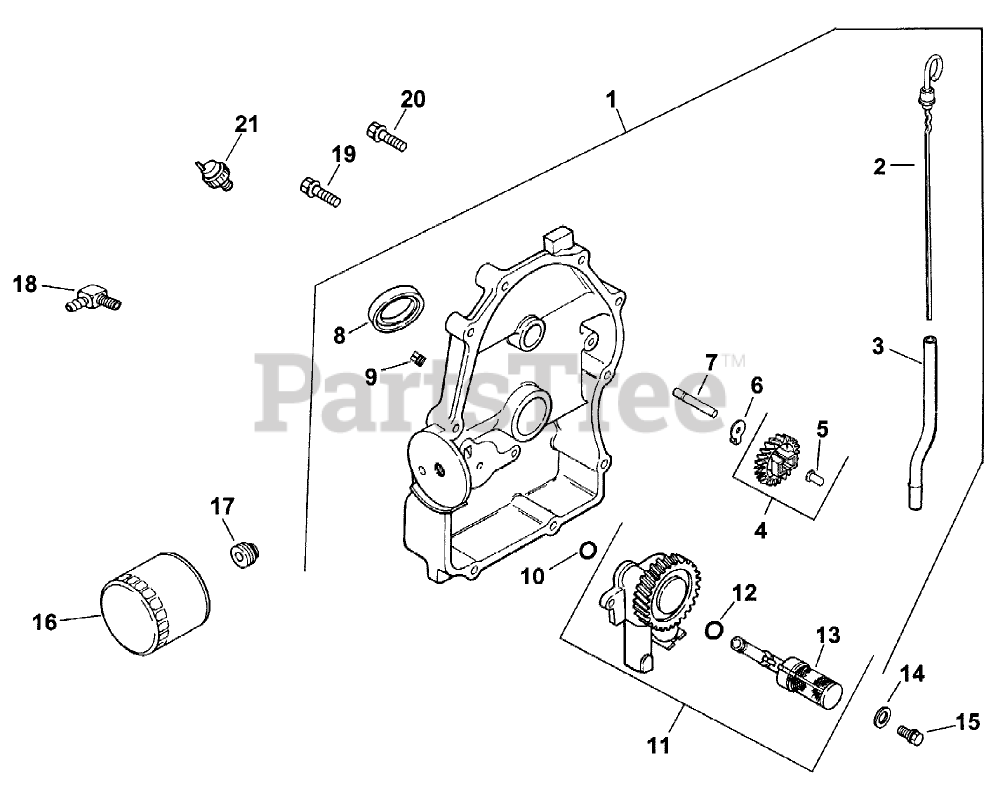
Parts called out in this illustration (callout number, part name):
1	Plate, closure assembly (Includes 2-12)
2	Dipstick
3	Tube-Dipstick
4	Kit, governor gear (Includes 5)
5	Pin-Governor
6	Tab-Locking
7	Shaft-Gear, Governor
8	Seal-Oil
9	Plug
10	O Ring
11	Oil pump assembly (Includes 12,13)
12	O-Ring
13	Pick Up-Oil
14	Washer
15	Screw
16	Filter-Oil
17	Nipple-Filter, Oil
18	Connector
19	Screw
20	Screw
21	Switch-Pressure
